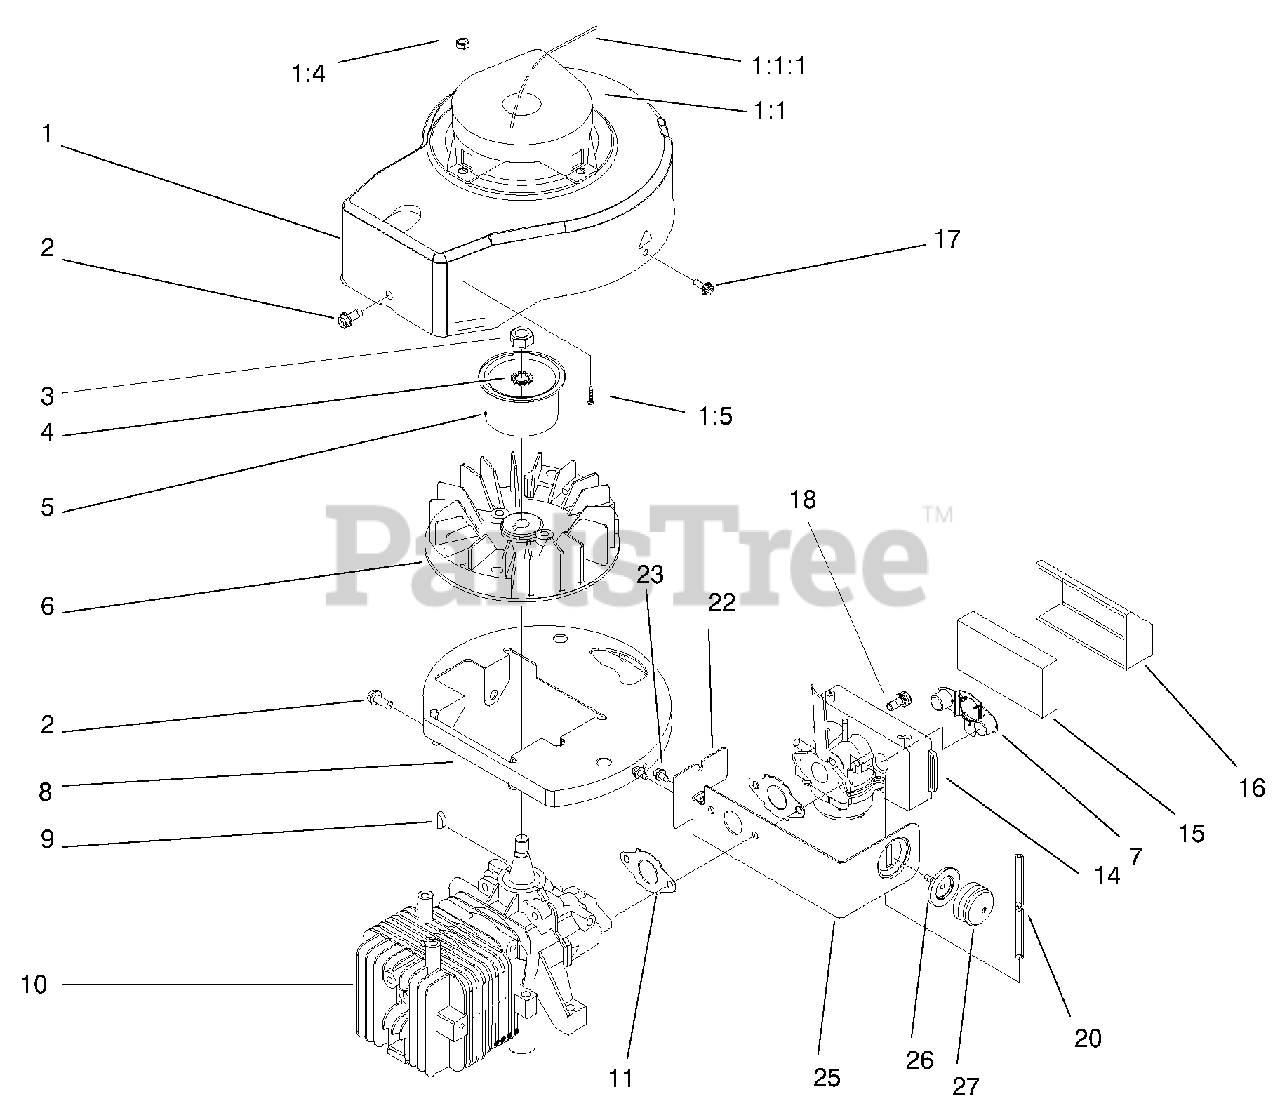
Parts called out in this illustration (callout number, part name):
1	Shroud/Start
1:1	Recoil
1:4	Nut-Lock
1:5	Screw-HWH
2	Screw
4	Washer-Lock
5	Hub Starter
6	Flywheel
7	Shield-Fuel
8	Shroud Base
10	Short Block ASM
11	Gasket-Carburetor
14	Carburetor ASM
15	Element-Air Filter
16	Cover-Air Filter
20	Hose-Primer
22	Shield-Governor
25	Shield Primer Mounting
26	Body-Primer
27	Bulb-Primer
